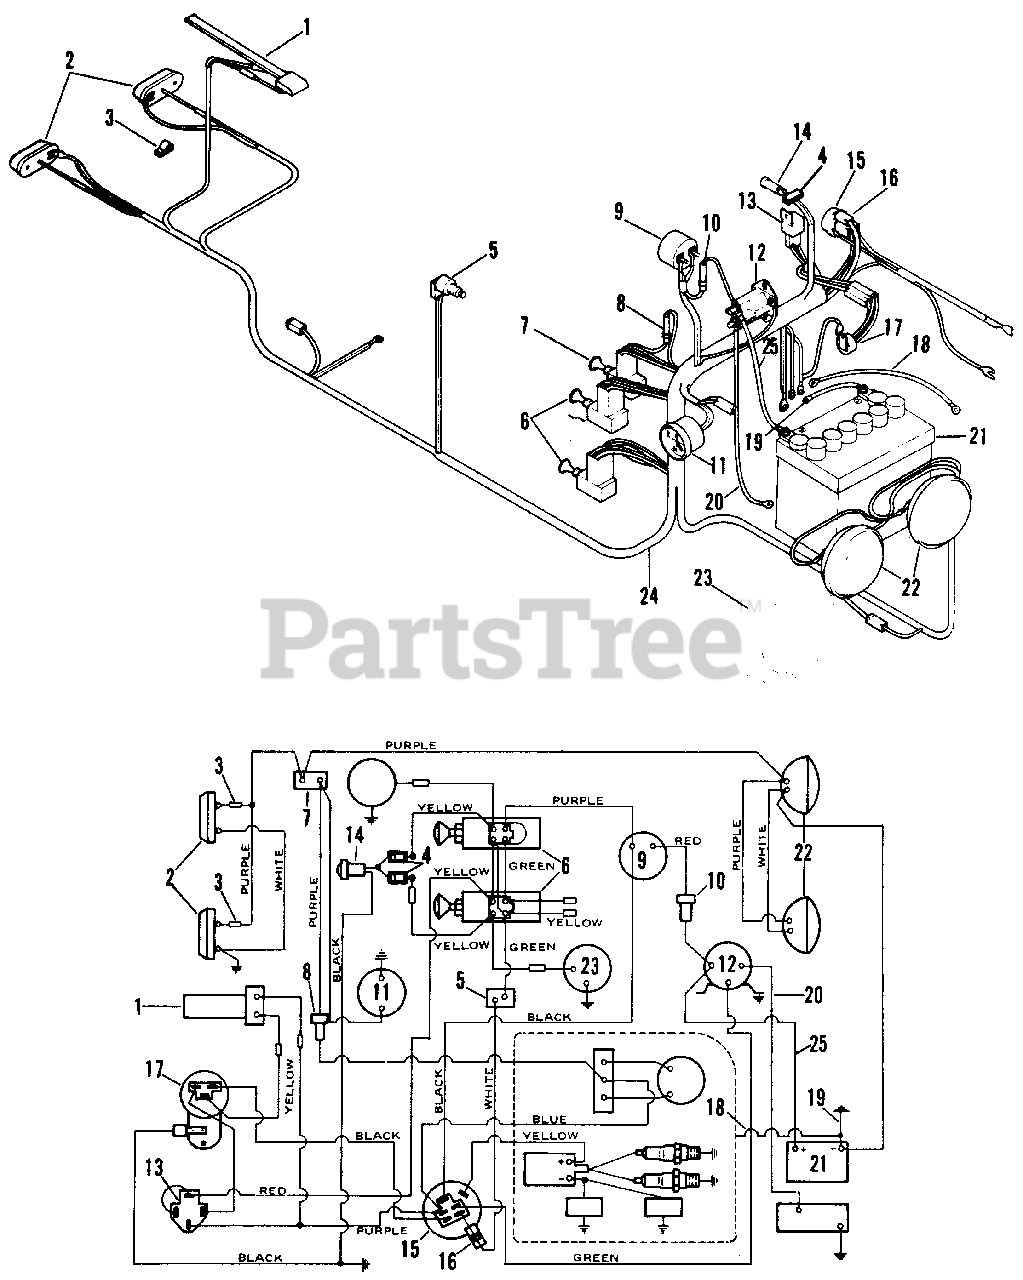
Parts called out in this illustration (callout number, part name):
1	Switch Seat
2	Tail Light Assembly
3	Wire Clip
4	Plug, Molded Diode
5	Safety Switch
6	Clutch Switch
7	Light Switch
8	SAE 7 Amp Fuse
9	Ammeter
10	SAE 30 Amp Fuse
11	Hourmeter
12	Solenoid
13	Relay
14	PTO Indicator Light
15	Switch and Key Set Assembly
16	Diode Assembly
17	Time Delay Module
18	Cable
19	Cable, Ground
20	Cable, Starter
21	Battery
22	Headlight
23	Clutch Assembly 1.12 Bore
24	Wiring Harness
25	Cable, Starter
NS	Jumper
